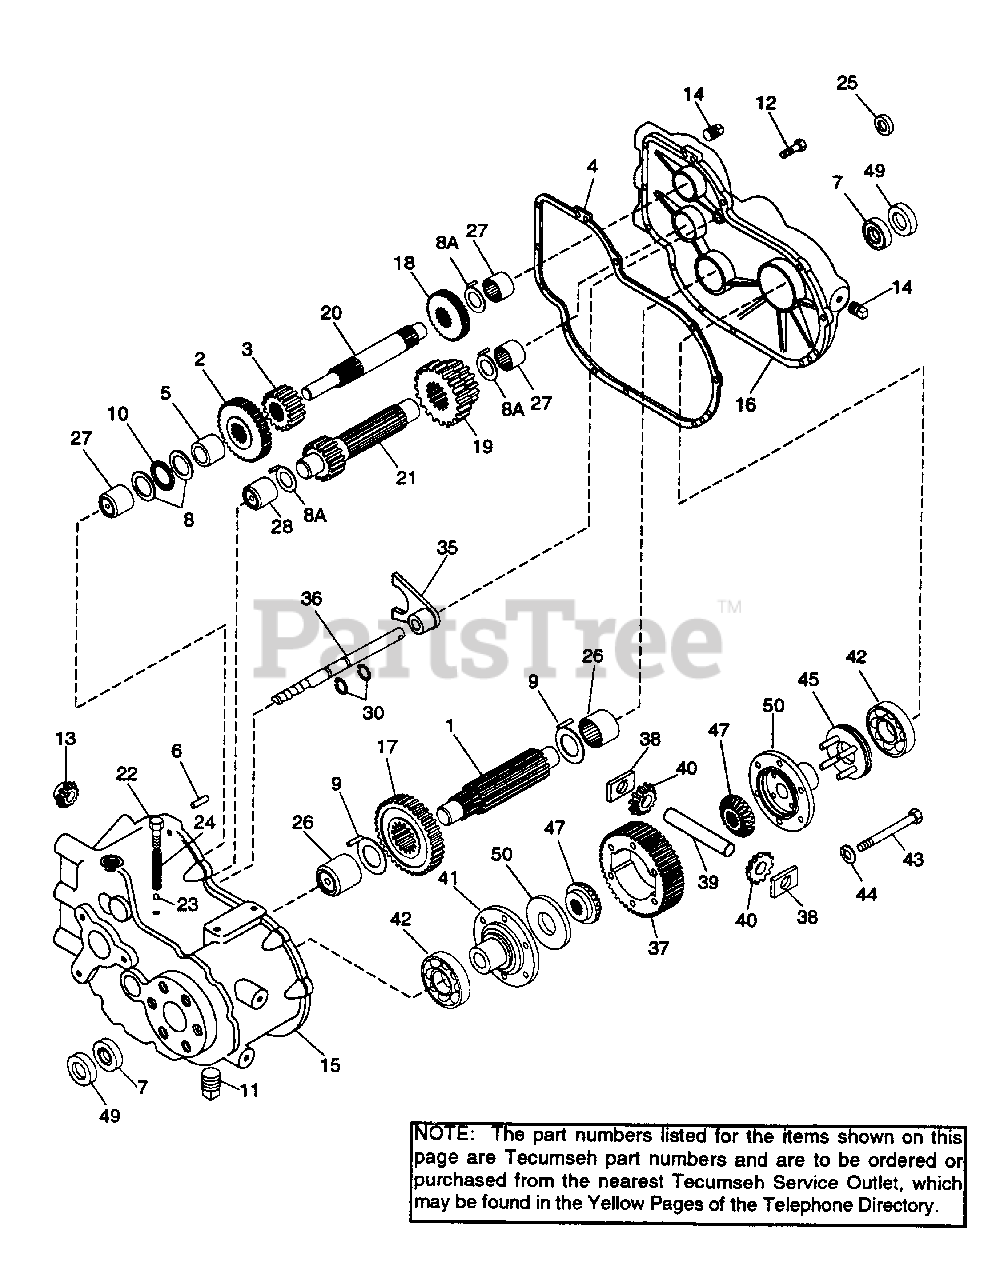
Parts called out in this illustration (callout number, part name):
1	PINION, OUTPUT
2	GEAR, BEVEL
3	GEAR, SPUR
4	GASKET, CASE & COVER
5	SPACER
6	PIN, DOWEL
7	SEAL, OIL
8	WASHER, THRUST
8A	WSHR, THRUST
9	WSHR, THRUST
10	BEARING, THRUST
11	PLUG, MAGNETIC DRAIN, 3/8-18
12	SCREW, HEX HD. THREADFORMING, 5/16-18 X 1
13	PINION, BEVEL
14	PLUG, PIPE, 1/8-27
15	CASE ASSY., TRANSAXLE
16	COVER, ASSY., TRANSAXLE
17	GEAR, OUTPUT
18	GEAR, SPUR
19	GEAR, CLUSTER
20	SHAFT, COUNTER
21	SHAFT & GEAR, SHIFTER
22	SCREW, HEX FLANGED HD., 1/4-20 X 5/8
23	BALL, STEEL, 3/16"
24	SPRING, SHIFTER FORK
25	SEAL, OIL
26	BEARING, NEEDLE
27	BEARING, NEEDLE
28	BEARING, NEEDLE
30	RING, RETAINING
35	FORK, SHIFT
36	ROD, SHIFT
37	GEAR, RING
38	BLOCK, DRIVE
39	PIN, DRIVE
40	PINION, BEVEL
41	CARRIER, DIFFERENTIAL
42	BEARING, BALL
43	SCREW, HEX FLANGED HD., 3/8-16 X 2-3/4
44	LOCKWASHER, 3/8"
45	CARRIER, DIFFERENTIAL
47	GEAR, BEVEL
49	SPACER
50	WASHER, THRUST
